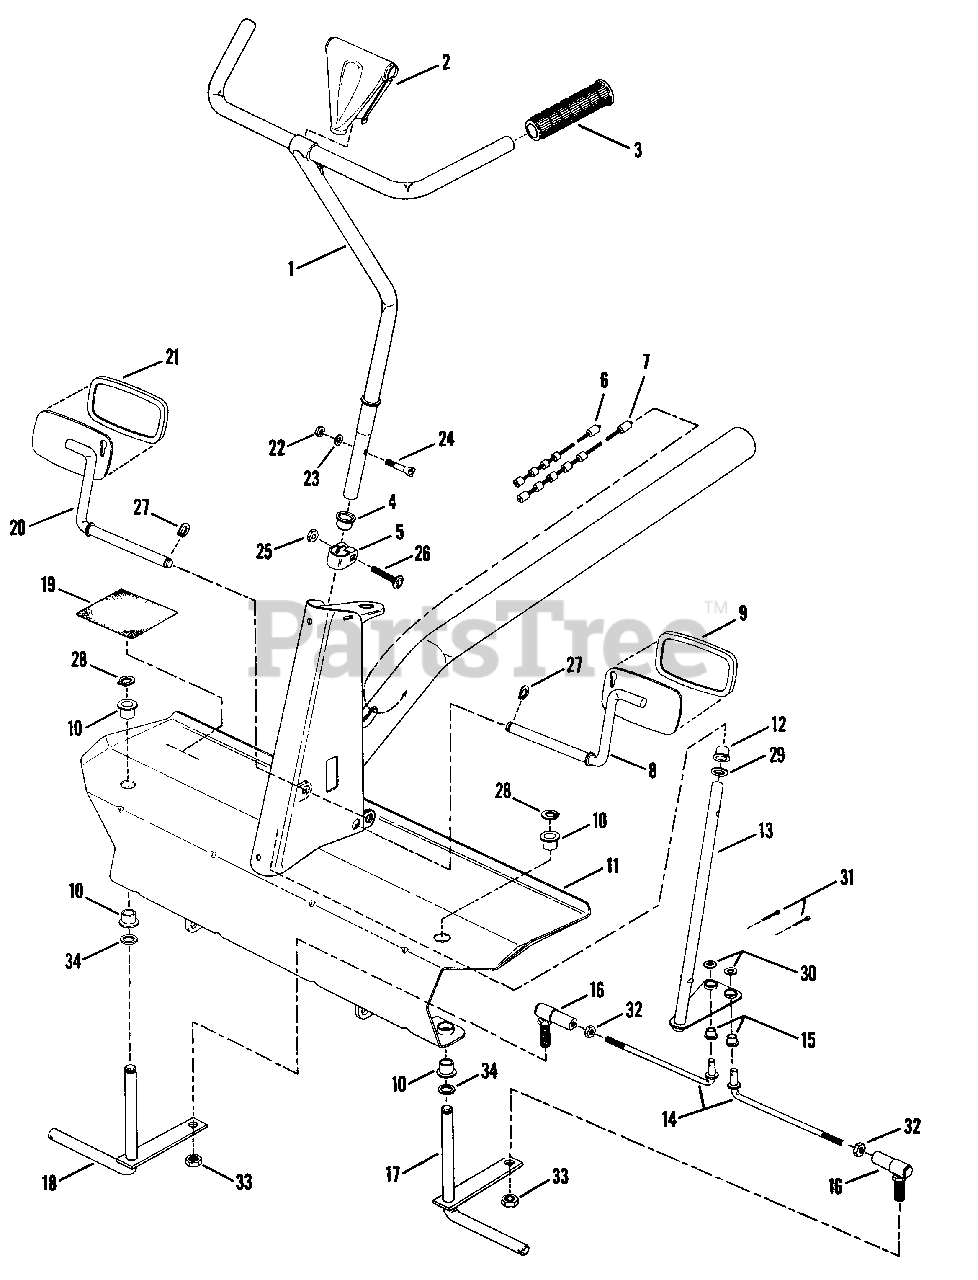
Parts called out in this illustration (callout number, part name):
1	HANDLE, Steering
2	COVER, Handle
3	GRIP, Handle
4	BUSHING, Nylon
5	CLAMP, Steering
6	CABLE, Auxiliary Brake 33 & 41"
7	CABLE, Clutch/Brake 33 & 41"
8	PEDAL, Clutch/Brake, Left Hand
9	PAD, Clutch/Brake Pedal
10	BEARING
11	FRONT AXLE STRUCTURE 33 & 41"
12	BUSHING, Nylon
13	SHAFT, Steering
14	TIE-ROD 33 & 41"
15	BUSHING, Tie-Rod
16	BALL JOINT, 3/8-24 Thread
17	King Pin, L.H.
18	King Pin, R.H.
19	PAD, Foot 28 & 30"
20	PEDAL, Auxiliary Brake, Right Hand
21	PAD, Auxiliary Brake Pedal
22	NUT, 1/4-28 Hex
23	LOCKWASHER, 1/4 Internal Tooth
24	BOLT, 1/4-28 Tapered Head
25	NUT, 5/16-18 Hex
26	CARRIAGE BOLT, 5/16-18x1-1/2"
27	RING, Retaining
28	RING, Retaining
29	WASHER, 5/8 SAE
30	WASHER, 3/8 SAE
31	COTTER-PIN, 1/8x3/4
32	NUT, 3/8-24 Hex
33	LOCKNUT, 3/8-24 Hex
34	WASHER, 3/4 SAE
